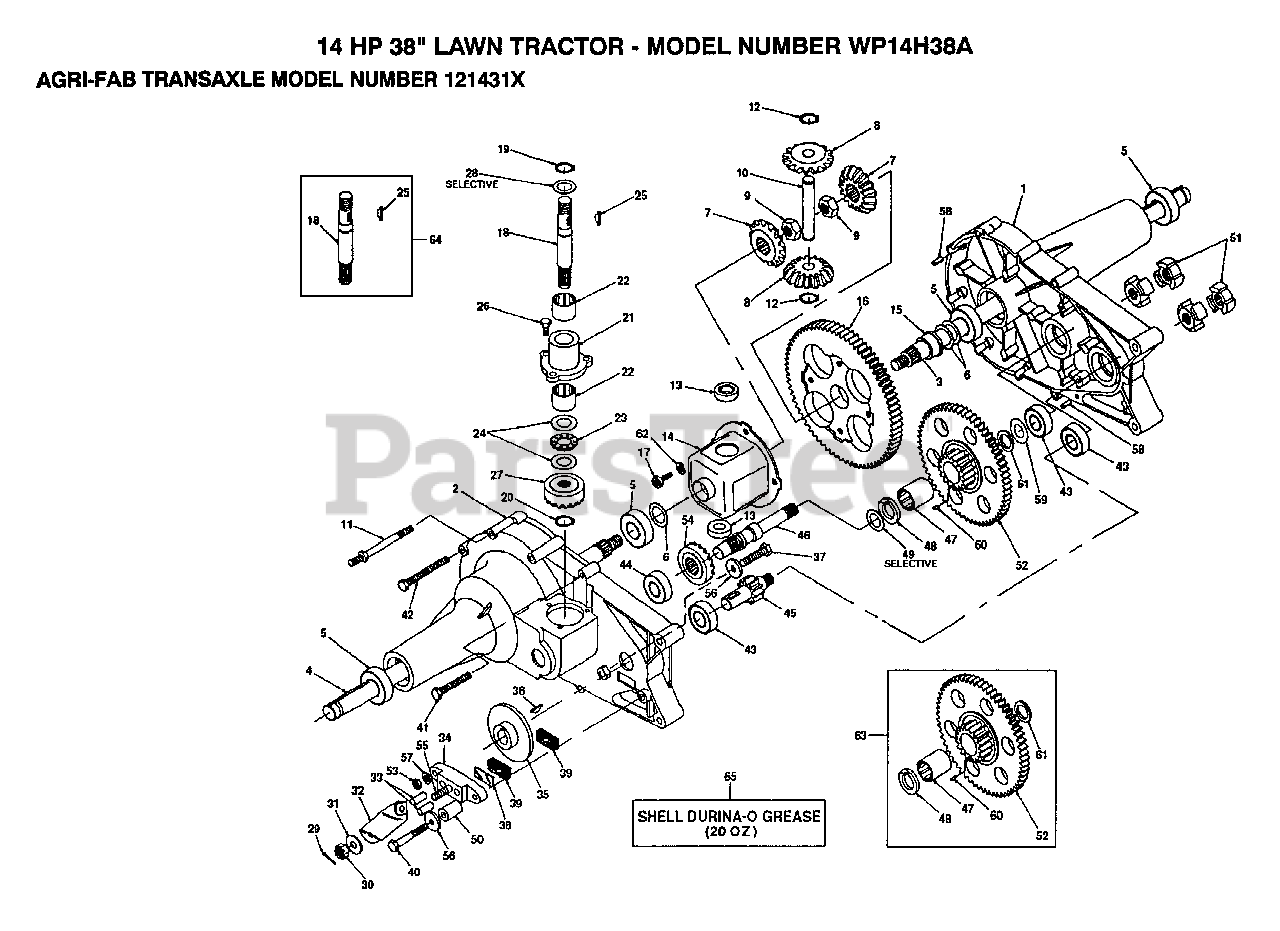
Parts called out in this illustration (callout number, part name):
1	HSG HALF LH-44077
2	HSG HALF RH-44076
3	AXLE LH -44273
4	AXLE RH-44272
5	BEARING.44121.AGR
6	WASHER -44008
7	GEAR MITER -44096
8	GEAR MITER -44097
9	NUT -44133
10	SHAFT CROSS
11	SCREW-STUD -44271
12	SNAP RING -44146
13	"THRUST, BEARING -44128"
14	HOUSING.ASM.DIFF.-62590
15	"FLANGE, BEARING-44129"
16	GEAR
17	BOLT -44126
18	SHAFT INPUT-44270
19	SNAP RING -44145
20	RET RING (44144)
22	"NEEDLE, BEARING 44099"
23	BEARING.NEE.44139
24	WASHER-44109
25	KEY.44136.HYDRO
26	SCREW
28	WASHER -44371
29	PIN COTTER -44101
30	NUT -44142
31	WASHER FLAT -44130
32	ARM BRAKE 23710
33	PIN BRAKE ACTUATO -44127
34	BRAKE YOKE
35	DISC BRAKE -(44090)
36	KEY -44143
37	SCREW -44277
38	PLATE PUCK -44134
40	SCREW -44300
41	SCREW -44123
42	SCREW -44124
44	"BALL, BEARING -44232"
45	SHAFT PINION 44083
46	SHAFT DRIVE-44080
47	NEEDLE BEARING -44342
48	THRUST.BRONZE -44343
49	WASHER -44371
50	SPACER -23711
51	COUPLING- 44084
52	GEAR.60/17.44523
53	NUT -43178
54	PINION-DR.44079
55	BOLT SQ HD
56	WASHER -44278
57	WASHER -44137
58	PIN ROLL-44269
59	WASHER -44125
60	DOWEL PIN -44346
61	SEAL GREASE -44394
62	WASHER.43177.AGRI
63	ASS'Y GEAR REDUCT
65	GREASE.50416.10OZ
